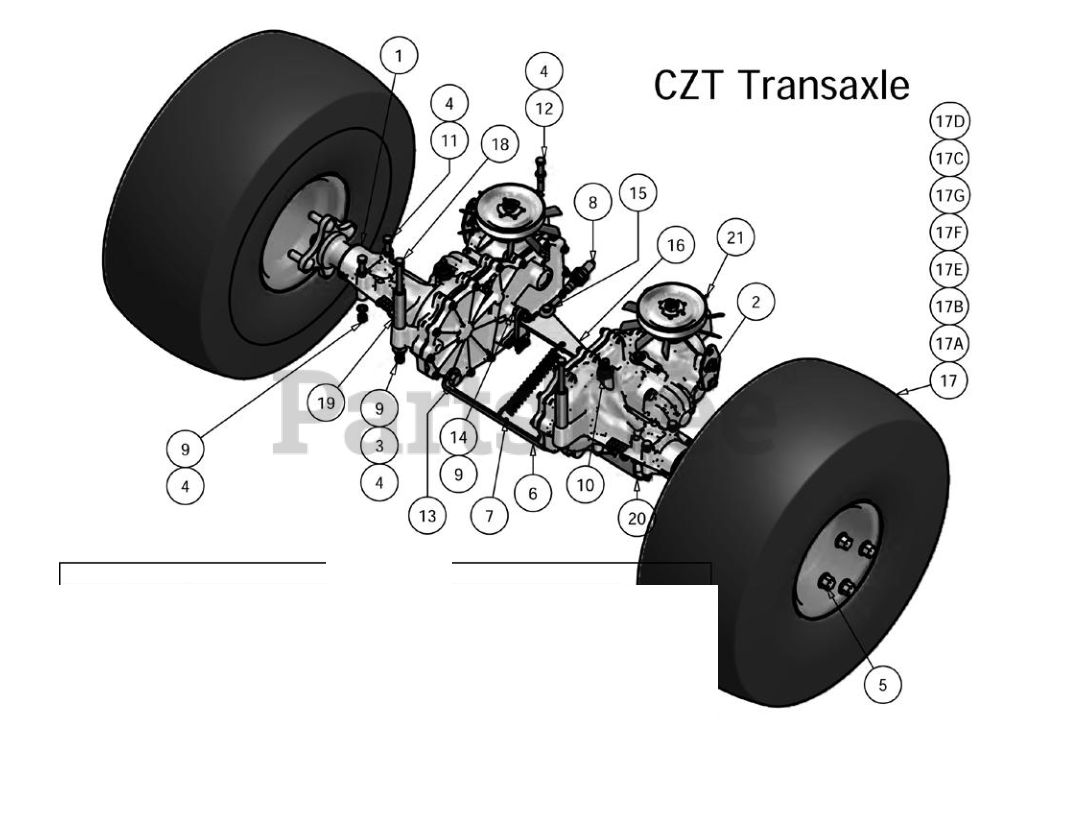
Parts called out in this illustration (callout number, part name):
4	5/16" Flat Washer
5	1/2" Lug Nut
6	Transaxle Support
8	Brake Cable
9	5/16" Hex Nut
10	45 Degree Fitting
11	5/16" x 3" Hex Bolt
12	5/16" x 2 1/2" Hex Bolt
13	3/8" x 2" Hex Bolt
14	1/4" x 1" Hex Bolt
15	1/4" x 3/4" Hex Bolt
16	Crossover Brake Bracket
17	23 x 10.50-12 Tire & Wheel (60" Only)
17A	23 x 10.50-12 Tire
17B	23 x 10.50-12 Wheel (60" Only)
17C	23 x 10.50-12 Tire & Wheel (50" Only)
17D	23 X 10.5-12 Wheel (50" Only)
17E	23 x 8.50-12 Tire & Wheel (42" Only)
17F	23 x 8.50-12 Tire (42" Only)
17G	23 x 8.50-12 Wheel (42" Only)
18	5/16" x 6" Bolt
19	3 1/4" Transaxle Spacer
20	Transaxle Filter
21	Fan/Pulley Kit
